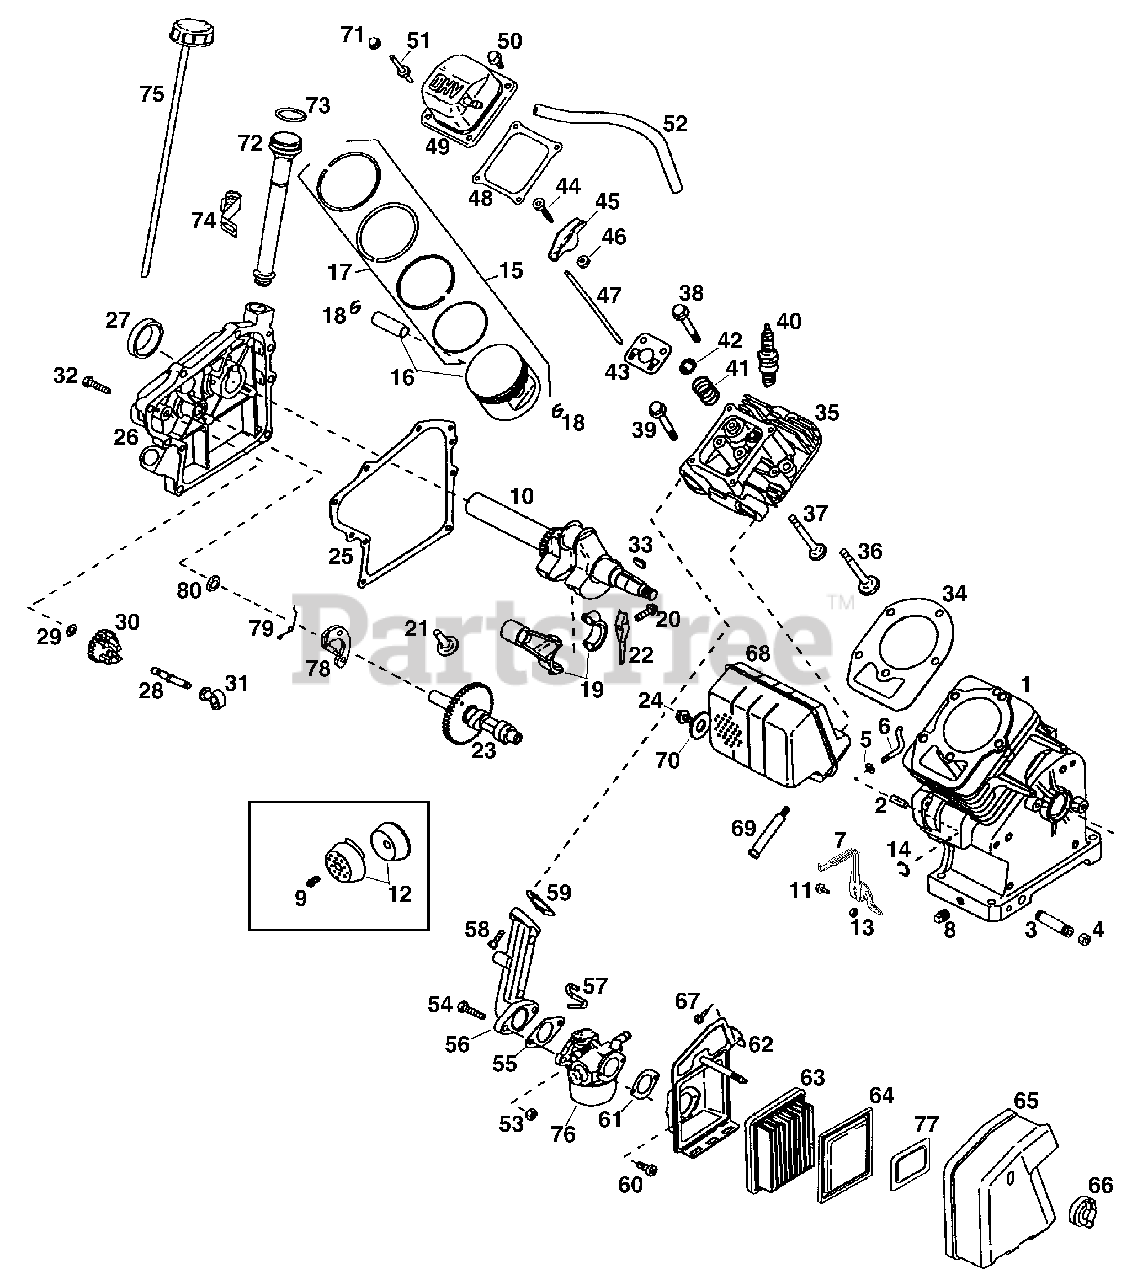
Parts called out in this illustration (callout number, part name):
1	Cylinder
2	Dowel Pin
3	Oil Drain Extension
4	Extension Cap
6	Governor Rod
7	Governor Lever
8	Oil Drain Plug
9	Screw, 8-32 x 3/8".
10	Crankshaft
11	Screw, Torx T-25, 10-32 x 63/64".
12	Spark Arrestor Kit
13	Lock Nut, 10-32
14	Retaining Ring
15	Piston, Pin & Ring Set (Standard)
16	Piston & Pin Ass’y (Standard)
17	Ring Set (Standard)
18	Piston Pin Retaining Ring
19	Connecting Rod Ass’y
20	Connecting Rod Bolt
21	Valve Lifter
22	Oil Dipper
24	Screw, 1/4-20 x 1-1/8".
25	Cylinder Cover Gasket
26	Cylinder Cover
28	Governor Shaft
30	Governor Gear Ass’y
31	Governor Spool
32	Screw, 1/4-20 x 1-1/4".
33	Flywheel Key
34	Cylinder Head Gasket
35	Cylinder Head
36	Exhaust Valve (Standard)
37	Intake Valve (Standard)
38	Screw, 5/16-18 x 1-1/2".
39	Screw, 5/16-18 x 2-41/64".
40	Resistor Spark Plug (N4C)
41	Valve Spring
42	Valve Spring Cap
43	Push Rod Guide
44	Rocker Arm Stud
45	Rocker Arm
46	Nut, 1/4-28
48	Rocker Arm Cover Gasket
49	Rocker Arm Cover
50	Screw, 1/4-20 x 31/64".
52	Breather Tube
53	Nut, 1/4-20
54	Screw, 1/4-20 x 1".
55	Carb. to Intake Pipe Gasket
56	Intake Pipe
57	Throttle Link
58	Screw, 1/4-20 x 1".
59	Intake Pipe Gasket
60	Screw, 10-32 x 1/2".
61	Air Cleaner Gasket
62	Air Cleaner Body
63	Air Cleaner Filter
64	Air Cleaner Filter (Poly)
65	Air Cleaner Cover
67	Screw, 10-32 x 31/64".
69	Screw, 1/4-20 x 2-9/32".
71	Nut & Lock Washer
72	Oil Fill Tube
74	Fill Tube Clip
76	Carburetor Ass’y
77	Air Cleaner Baffle
78	Compression Release Weight
79	Compression Release Spring
